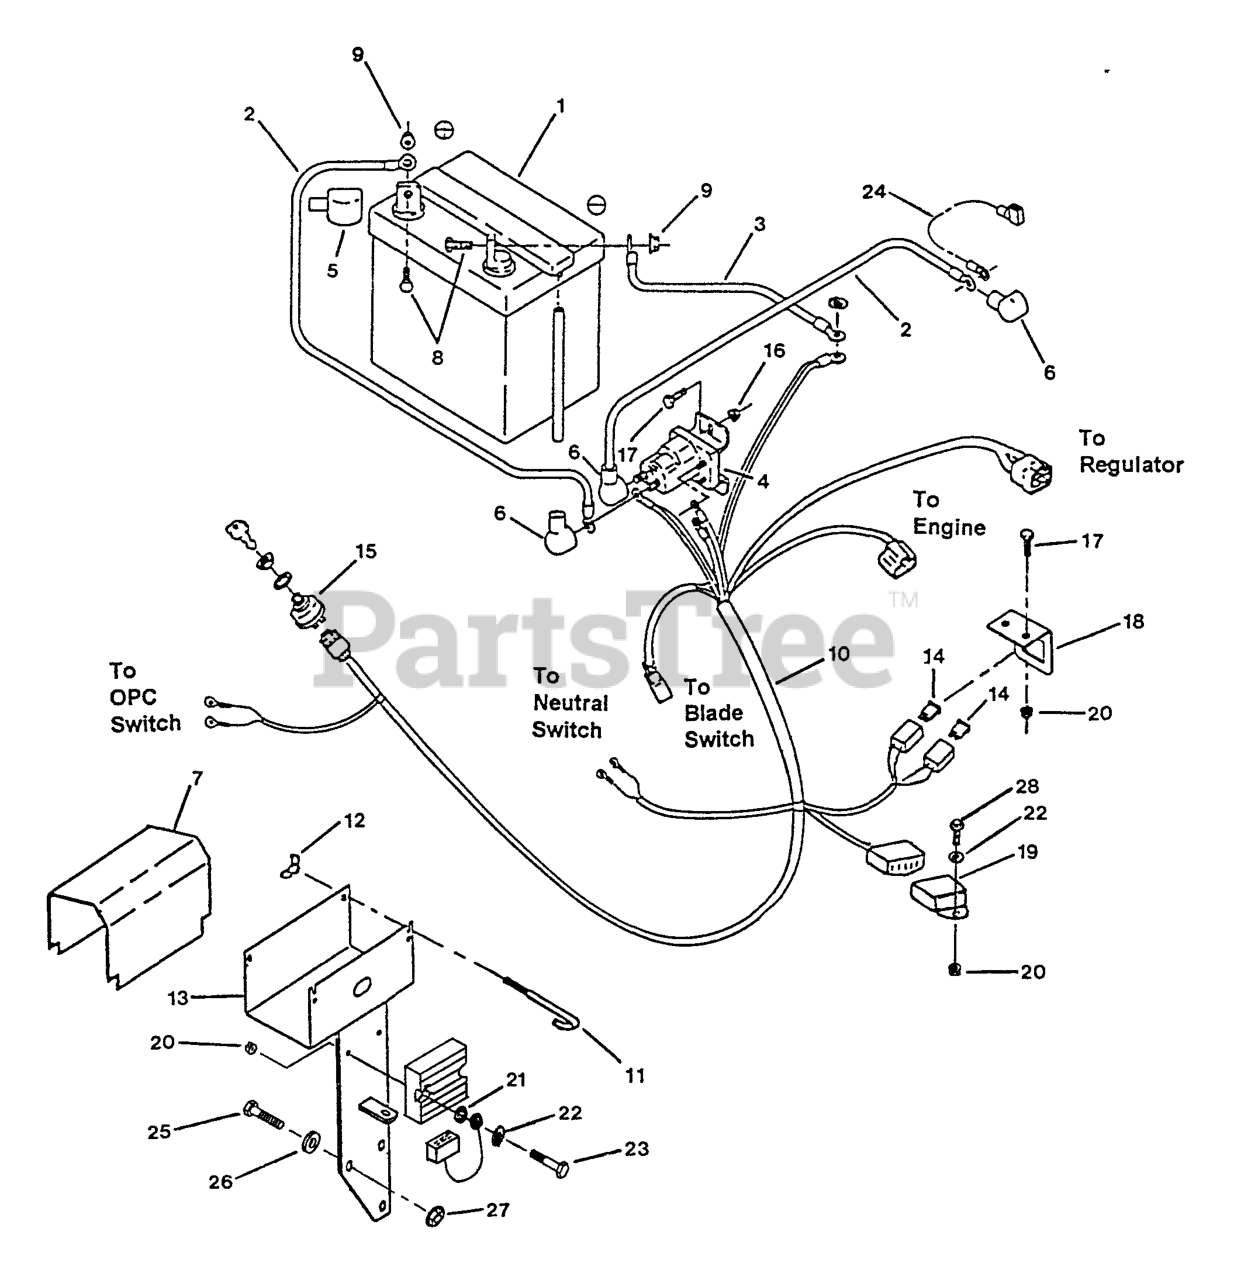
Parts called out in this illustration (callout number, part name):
1	Battery 12v Manifold
6	INSULATOR-SOLENOID
10	HARNESS,WIRING METRO
11	BOLT - HOLD DOWN
12	WINGNUT
15	SWITCH,IGNITION
18	BRACKET,FUSE
